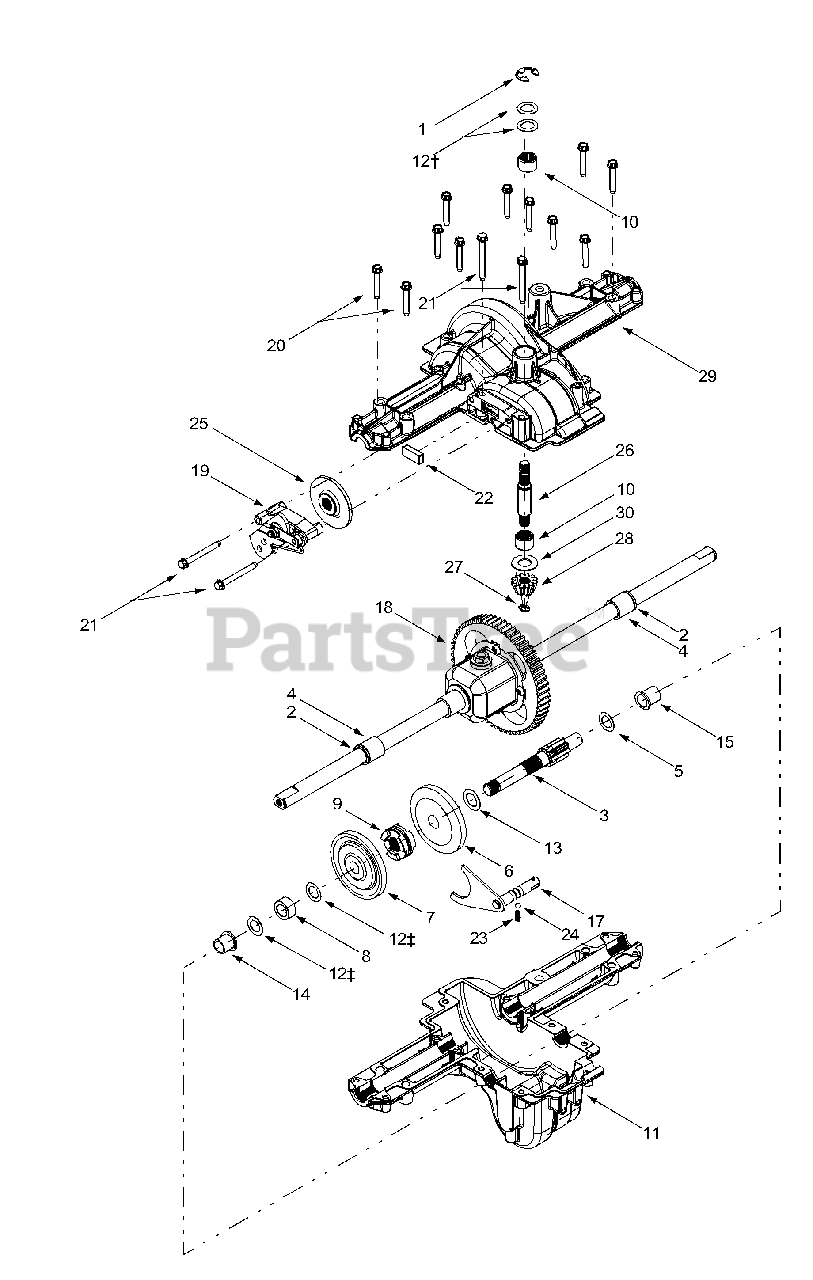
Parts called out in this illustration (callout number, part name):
1	E-ring, .75
2	Seal, .75 x 1.0 x .125
3	Drive Shaft
4	Sleeve Bearing, .75 x .1.0 x 1.0
5	Thrust Washer, 1.0 x .632 x .0
6	42-tooth Bevel Gear
7	42-tooth Bevel Gear
8	Spacer, .633 x 1.0 x .513
9	Clutch Collar
10	Needle Bearing, .625 x .875
11	Lower Housing
12	Flat Washer, 5/8 x 1.0 x .030
13	Flat Washer, .70 x 1.125 x .031
14	Flange Bearing, 5/8 x 3/4 x 3/4
15	Flange Bearing, 5/8 x 3/4 x 15/16
17	Detent Shaft Assembly
18	Differential Assembly
19	Brake Assembly
20	Self-tapping Screw, 1/4-20 x 1.625
21	Self-tapping Screw, 1/4-20 x 2.375
22	Brake Pad
23	Compression Spring
24	Detent Ball
25	Brake Disc
26	Input Shaft
27	Retaining Ring, .437
28	14-tooth Bevel Pinion
29	Upper Housing
30	Thrust Washer, .635 x 1.25 x .042
